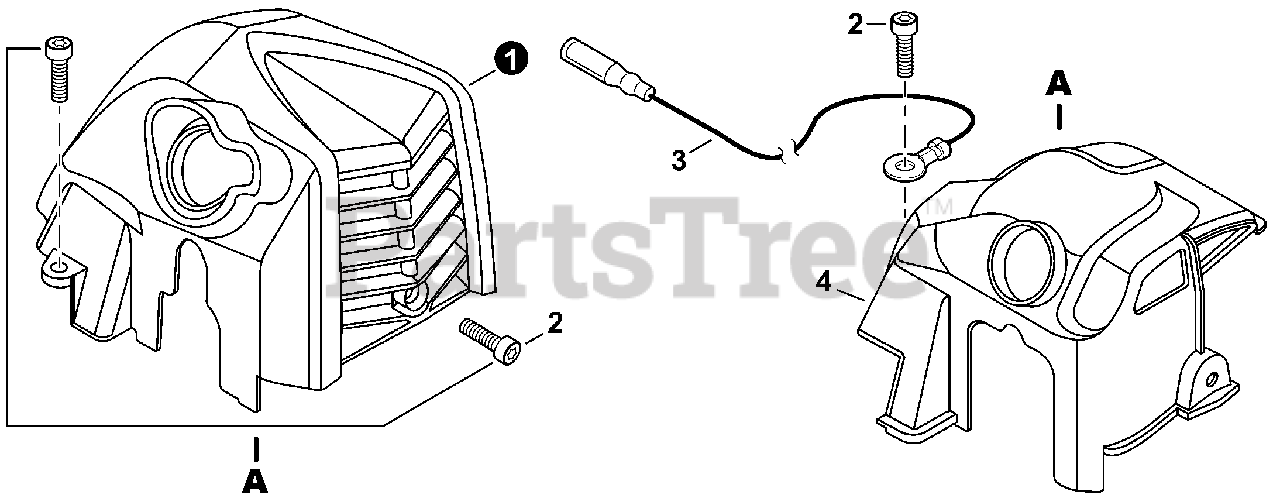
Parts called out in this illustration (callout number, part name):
1	COVER, ENGINE
2	BOLT, TORX 5x12
4	COVER, CYLINDER
